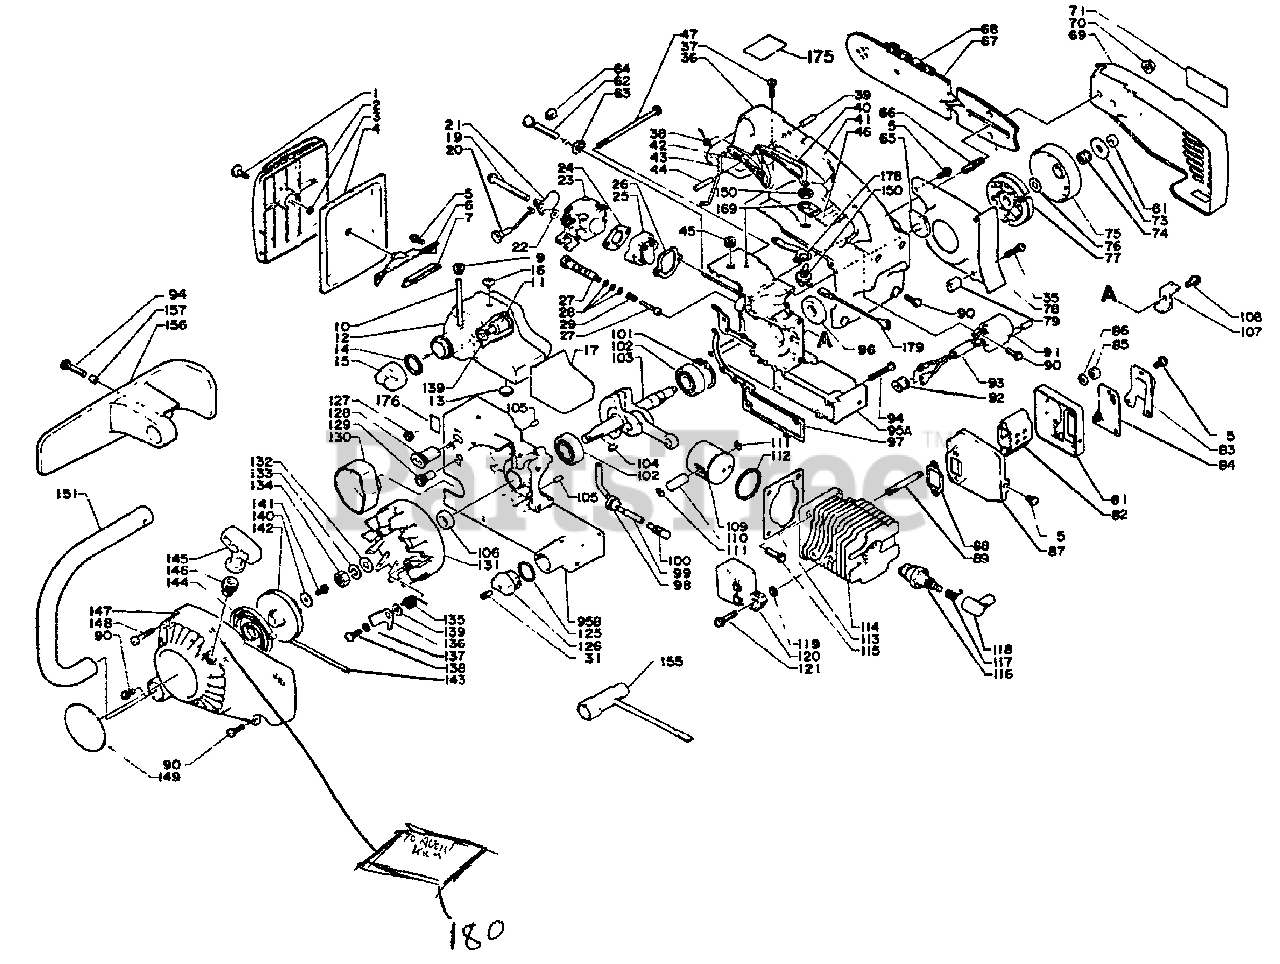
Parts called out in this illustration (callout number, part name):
1	THUMBSCREW
2	COVER, AIR FILTER
3	RING, RETAINING - 4
4	FILTER, AIR
5	SCREW - 4X10
6	BRACKET, AIR CLEANER
7	CUSHION
9	GROMMET
10	PIPE - FUEL
11	FILTER, FUEL
12	TANK, FUEL
13	CAP ASSY
14	GASKET, CAP
15	CAP
17	CUSHION
19	SCREW - 5X55
20	ROD, CHOKE
21	SHUTTER, CHOKE
22	WASHER
23	CARBURETOR C1S-K1D
24	GASKET, INTAKE
25	INSULATOR
26	GASKET, INTAKE
27	AUTO-OILER ASSY
28	O-RING - 5
31	VENT, TANK
35	SCREW - 4X20
36	HANDLE - TOP
37	SCREW - 4X18
38	SPRING
39	PIN - SPRING -- 5X18
40	LOCKOUT, THROTTLE
41	GRIP, HANDLE
42	TRIGGER, THROTTLE
43	ROD, THROTTLE
44	PIN - SPRING -- 5X25
46	LABEL
61	LOCKNUT - 6
62	SCREW, TENSIONER
63	TENSIONER, CHAIN
65	PLUG
66	STUD, GUIDE BAR
67	GUIDE BAR
68	SAW CHAIN
69	GUARD, SPROCKET
70	NUT - 6 -- FLANGE
71	LABEL - ECHO
74	BEARING, NEEDLE
75	DRUM, CLUTCH
77	CLUTCH ASSY
78	PLATE, SEAL
79	SPACER
79	MUFFLER ASSY
81	LID, MUFFLER
82	BAFFLE, MUFFLER
83	GUIDE, EXHAUST
84	SCREEN, SPARK ARRESTOR
85	SCREW - 4X8
87	GUIDE, EXHAUST
88	GASKET, EXHAUST
90	SCREW - 4X16
91	COIL, IGNITION
94	SCREW - 4X30
95	CRANKCASE KIT
96	SEAL, OIL
97	GASKET, CRANKCASE
98	GROMMET
99	PIPE - OIL
100	FILTER, OIL
101	RING, RETAINING - 32
102	BEARING, BALL - 6201
103	CRANKSHAFT ASSY
105	PIN - LOCATING
106	SEAL, OIL
107	CATCHER, CHAIN
108	SCREW - 5X10
109	PISTON
110	PIN, PISTON
111	RING, RETAINING
112	RING, PISTON
113	GASKET, CYLINDER
114	CYLINDER
115	SCREW - 5X20
116	SPARK PLUG -- CJ-8Y
117	TERMINAL, SPARK PLUG CAP
118	CAP, SPARK PLUG
119	SPACER
120	COIL, IGNITION
121	SCREW - 5X22
125	O-RING - 16
126	CAP ASSY
128	GROMMET
129	GROMMET
130	SEAL
131	FLYWHEEL
132	WASHER - 8
133	LOCKWASHER - 8
135	SPRING, RETURN
136	PAWL, STARTER
138	SCREW
139	WASHER - 5
139	STARTER ASSY
140	WASHER - 4
141	SCREW - 4X10
142	REEL, ROPE
143	ROPE, STARTER - 3.5X850
144	SPRING, REWIND
145	GRIP, STARTER
146	GUIDE, ROPE
147	CASE, STARTER
148	SCREW - 4X25
149	LABEL - ECHO
150	IGNITION SWITCH KIT
151	HANDLE - FRONT
155	T-WRENCH - 10X19mm
156	GUARD
169	LABEL - SWITCH
175	LABEL - NOISE
176	LABEL - CHOKE
178	PLATE - GROUND
179	LEAD - GROUND
180	SCREW - 4X16
181	SCREW - 4X22
183	PLATE, PREVENT
192	PLATE, STARTER
